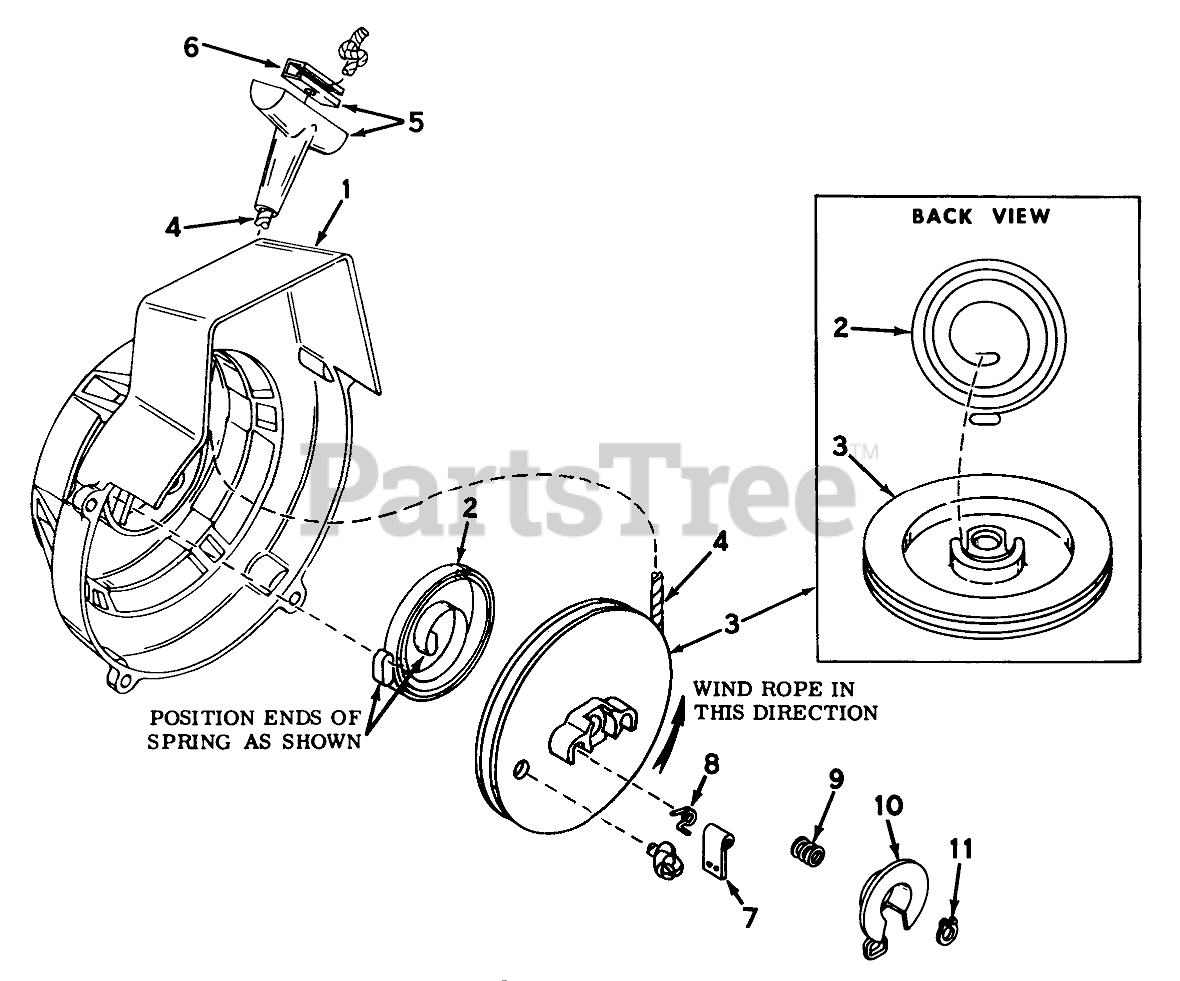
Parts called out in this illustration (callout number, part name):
1	Housing Assy., Shroud & Starter
2	Spring, Rewind
3	Pulley, Starter Rope (Incl. No. 8)
4	Rope, Starter
5	Handle Assy., Starter Rope (Incl. No. 6)
6	Insert, Handle
7	Dog, Starter
8	Retum Spring, Left Hand Wound
9	Spring, Brake
